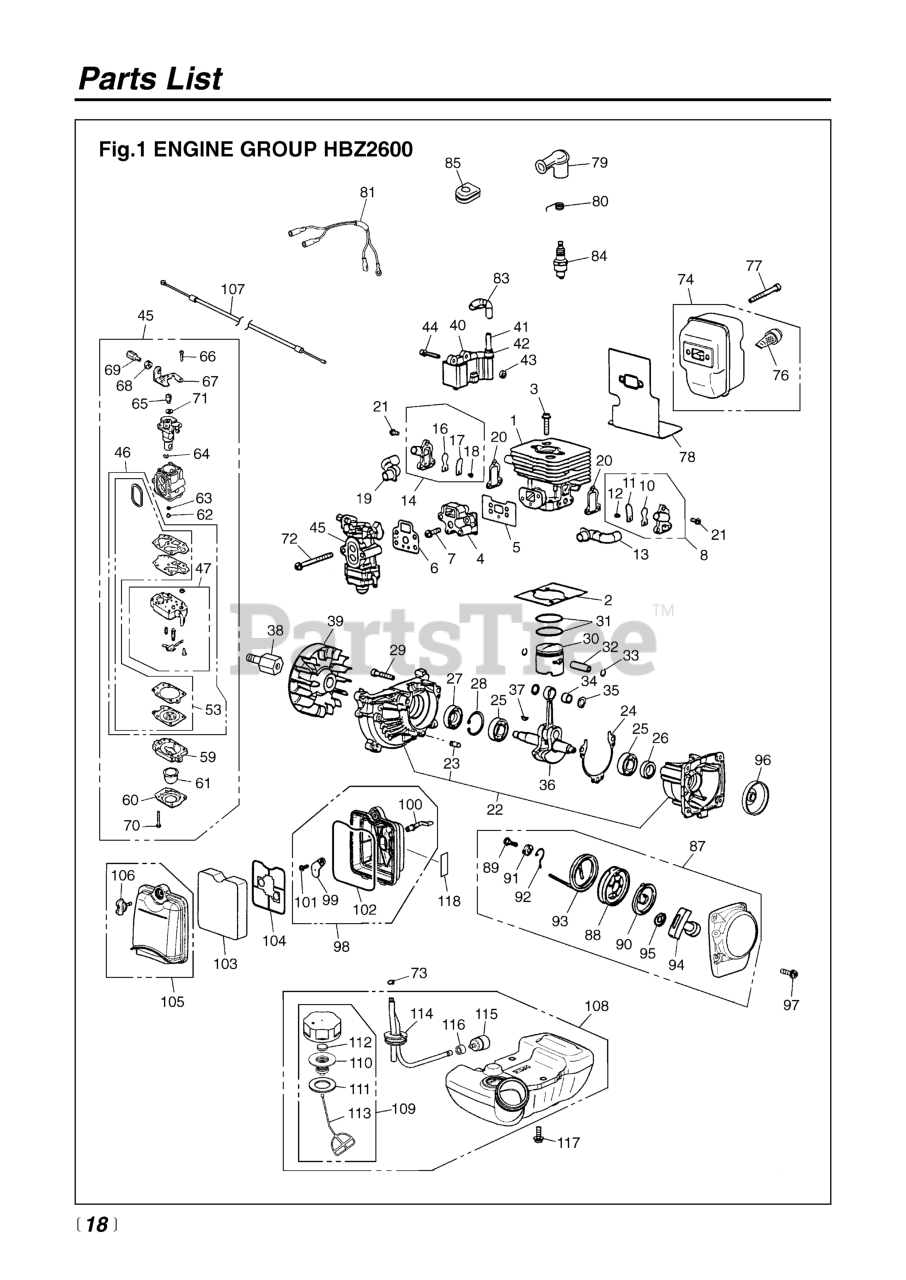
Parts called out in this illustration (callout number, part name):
1	CYLINDER (RPLS. 4810-12111)
2	GASKET, BASE
3	BOLT
4	INSULATOR (RPLS. -13160/13161)
5	GASKET INSULATOR
6	GASKET, CARBURETOR
7	BOLT (RPLS 2850-14220)
8	REED VALVE (RPLS 4810-16110)
10	VALVE, REED
11	STOPPER
12	SCREW, M3 x 8
13	PIPE, AIR
14	REED VALVE (F) (RPLS. -1611)
16	VALVE, REED
17	STOPPER
18	SCREW, M3 x 8
19	PIPE, AIR (F)
20	GASKET, VALVE
21	BOLT, TORX
22	CRANKCASE-C
23	PIN
24	GASKET
25	BEARING
26	SEAL
27	SEAL, OIL (RPLS 1140-21220)
28	RING, SNAP, M28 x 1.2
29	BOLT
30	PISTON
31	RING, PISTON
32	PIN
33	RING, SNAP (RPLS 1101-41320)
34	BEARING (RPLS 1140-41330)
35	WASHER
36	CRANKSHAFT COMPLETE
37	KEY
38	EXTENSION
39	ROTOR
40	COIL-A
41	CORD (BLACK)
42	CAP
43	SPACER (RPLS -71260)
44	BOLT TORX
45	CARBURETOR (RPLS. T1513-81000)
46	REBUILD KIT
47	BODY-A
53	KIT, GASKET (REPLACES-06020)
59	BODY, PURGE
60	COVER, PUMP
61	PUMP, PRIMING
62	JET (USE -81251)
63	RING, O
64	RING
65	SWIVEL
66	SCREW
68	NUT, CABLE ADJUSTER
69	SCREW, CABLE ADJUSTER
70	SCREW
71	WASHER
72	BOLT
73	CLIP
74	MUFFLER-ASSY
76	ARRESTER
77	BOLT,TORX, M5X70
78	GASKET
80	SPRING
83	TUBE
84	PLUG, SPARK (RPLS 4810-73110)
85	GROMMET
87	RECOIL ASSEMBLY
88	REEL
89	SCREW
90	SPRING, SPIRAL
91	COLLAR
92	ARM
93	ROPE (REPLACES 4500-75160)
94	KNOB (RPLS -75420)
95	PLATE, STOPPER
96	PULLEY
97	BOLT
98	BODY A
99	PLATE, CHOKE
100	LEVER
101	SCREW
102	PACKING
103	ELEMENT
106	KNOB
107	CABLE COMP (RPLS, -83100)
108	TANK ASSY (RPLS-85001)
109	CAP ASSY (RPLS -85201)
110	HOLDER (REPLACES -85230)
111	PACKING
112	FILTER
113	STOPPER
114	PIPE COMPLETE
115	FILTER ASSY
117	BOLT
118	LABEL
